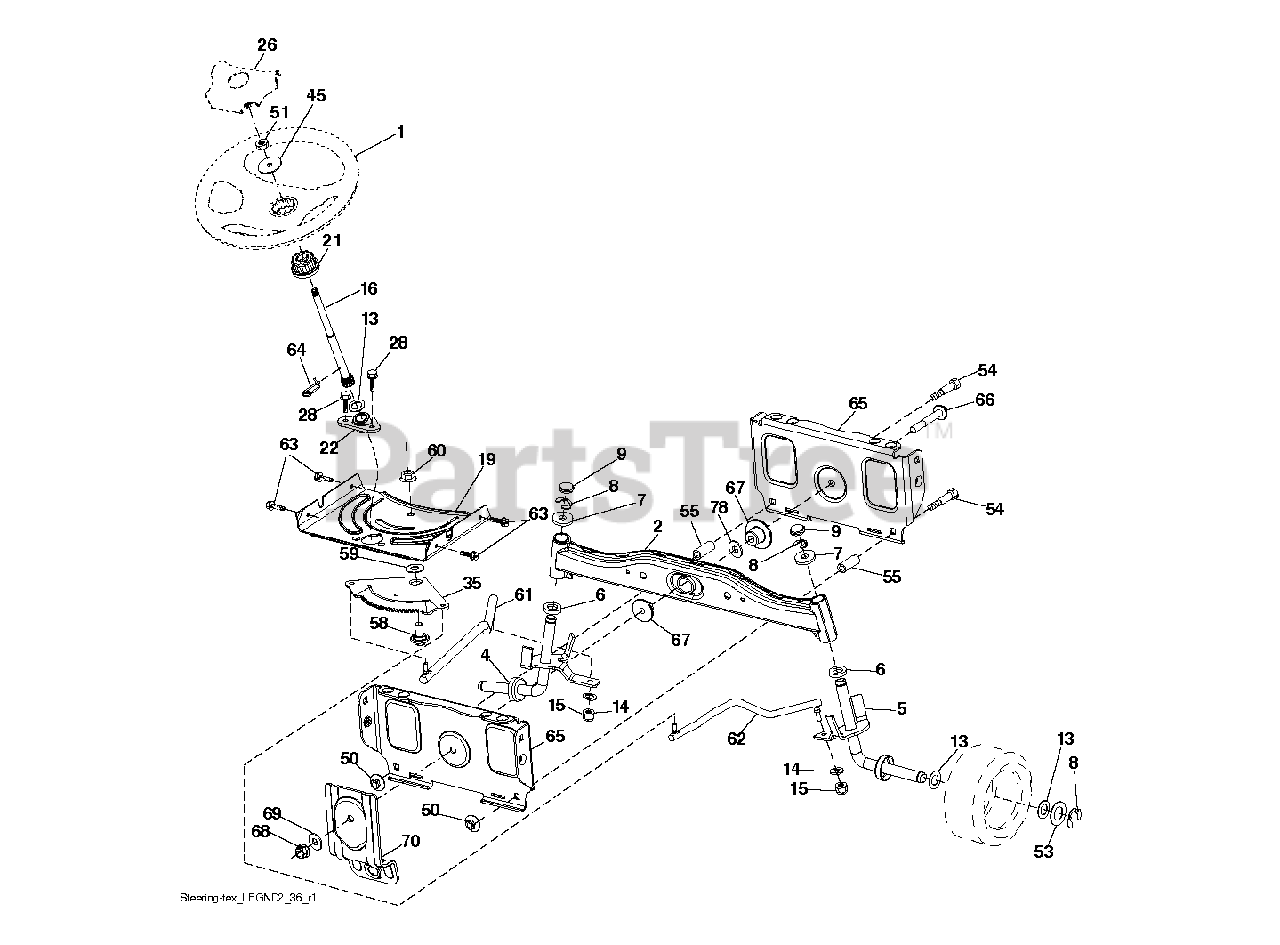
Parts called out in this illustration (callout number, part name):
1	WHEEL.STEER.HUSQ.SR.498.OVMLD
2	AXLE.CAST.IRON
4	SPINDLE.WELDED.LH.16"TEX
5	SPINDLE.WELDED.RH.16"TEX
6	THRUST WASHER
9	CAP.SPINDLE.BLACK
14	WASHER, LOCK 3/8
15	NUT CROWNLOCK 3/8-24
16	SHAFT, STEERING
19	PLATE.STEER.DDL.NLT/NG
21	ADAPTER, WHEEL STNG..
22	STEERING.SUPT.LOWER.
26	INSERT.CAP.WHL.STRG.HUSQ.PREM
28	SCREW, 3/8-16X3/4
35	GEAR.SECTOR.PLATE.DDL.
45	WASHER 9/16"ID, 2 3/8"OD
50	NUT LOCK FLG 3/8-16 UNC
51	NUT.HEX.1/2-20
53	WASHER.HARDENED
55	SPACER.BRACE.AXLE
58	BOLT.SHOULDER.SECTOR.P
59	WASHER.THURST.SECTOR.S
60	NUT FLANGE LOCK 5/8-11
61	DRAGLINK.LH.BALLSTUD.D
62	DRAGLINK.RH.BALLSTUD.D
63	SCREW
64	RETAINER.CLIP.SPRING.S
65	BRACE.AXLE.FRONT.NLT/N
66	BOLT HEX FGHD 7/16-14 X 3 SERR
67	BUSHING.PM.FRONT AXLE
68	NUT.LOCK.FLANGE.7/16
69	WASHER.1.5X.505X.118
70	BRKT.DECK.SUSPENSION.F
78	THRUST WASHER
